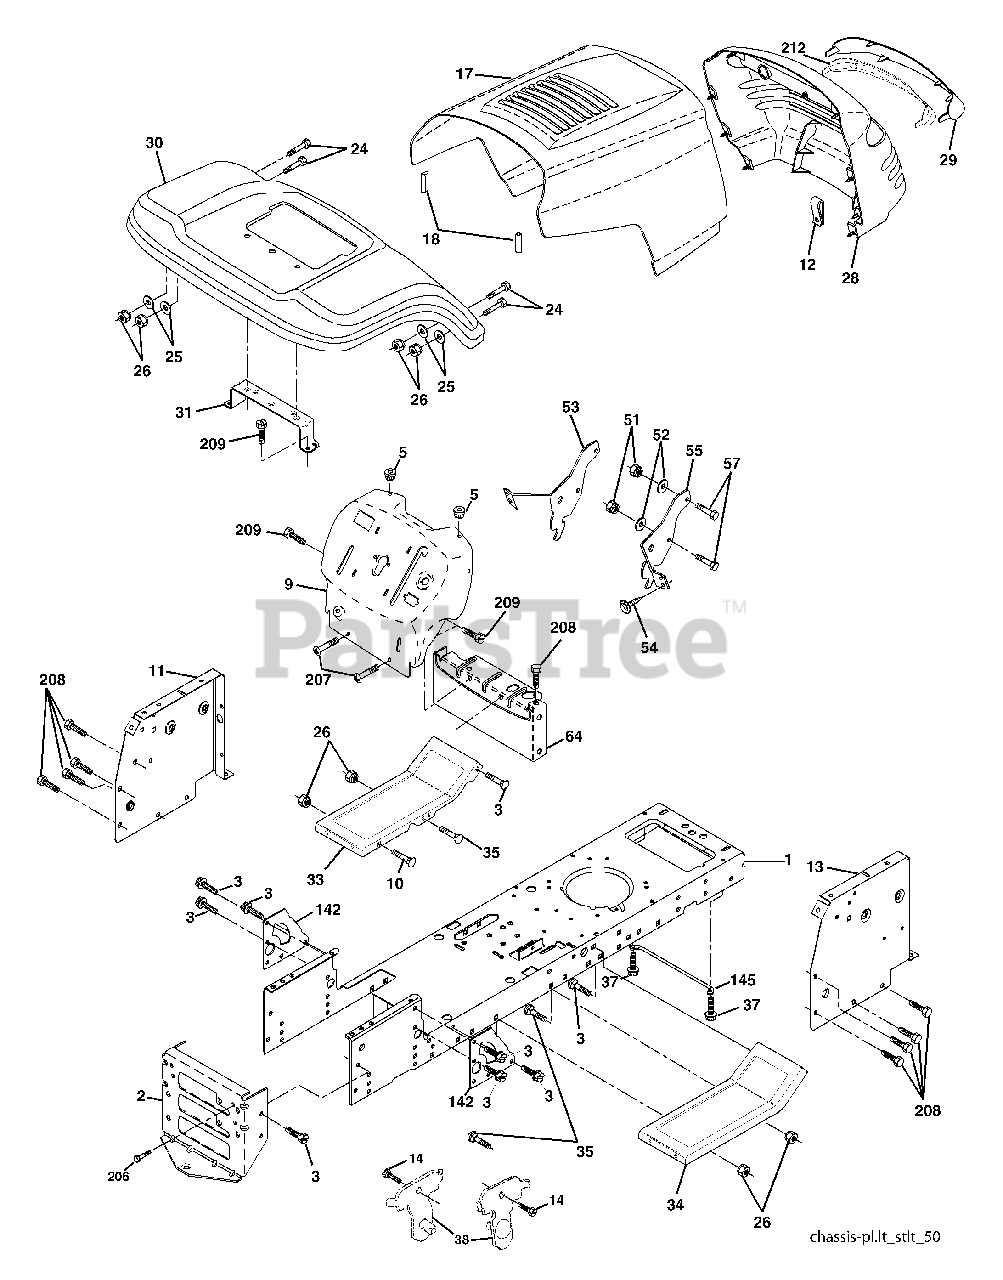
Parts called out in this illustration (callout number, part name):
1	Chassis
2	Drawbar, Stretch
3	Screw 3/8-16 x 3/4
5	Bumper, Hood/Dash
10	Bolt, Carriage 3/8-16 x 1
11	Panel Dash LH
12	Clip Tinnerman Grille P.L
13	Panel Slkscr Dash RH
14	Screw Thdrol 3/8-16 x 1/2
17	Hood
18	Bumper Hood
24	Bolt Fin Hex 3/8-16unc X 1 Gr. 5
25	Washer 13/32 X 13/16 X 12 Ga
26	Nut Lock Hex w/Ins 3/8-16 Unc
28	Grille/Lens Asm.
29	Lens Grille Private Label
30	Fender
31	Bracket Fender Repl 109873x
33	Footrest Pnt LH
34	Footrest Pnt RH
35	Bolt Rdhd Sht Sqnk 3/8-16 X3/4
37	Screw Thdrol 5/16-18 x 1/2 TYT
38	Bracket Asm. Pivot Mower
51	Nut Lock W/Insert 1/4-20unc
52	Washer 9/32 x 7/8x16 Ga.
53	Bracket Grille Lh
54	Screw Hex 8-18 x 7/8
55	Bracket Grille Rh
57	Bolt Fin Hex 1/4-20 unc x .75
64	Dash Lower
142	Plate Reinforcement
145	Rod Pivot Chassis/Hood
206	Bolt Shoulder 5/16-18
207	Screw Thdrol 5/16-18 x 1/2
208	Screw Thdrol 3/8-16 x 1/2
209	Screw Hex Wsh THDR 3/8-16 x 3/4
212	Insert Lens Reflect
